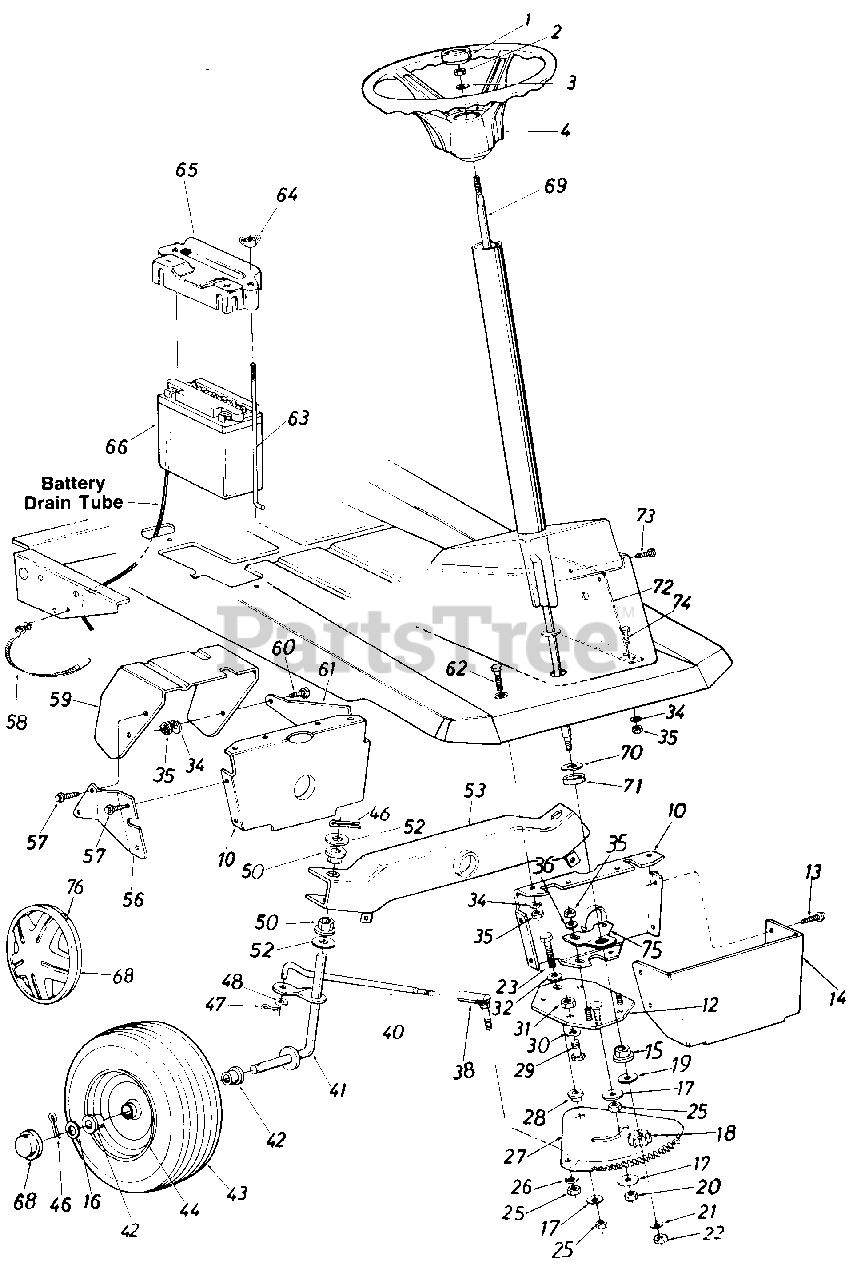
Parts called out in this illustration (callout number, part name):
1	Steering Wheel Cap
2	Hex L-Nut 5/16-24 Thd.
3	Bell-Wash. .345" I.D. x .88" O.D.
4	Steering Wheel Ass'y.
16	Fl-Wash. .64" I.D. x 1.5" O.D.
17	Fl-Wash. 3/8" I.D. x 1.37" O.D.
18	Steering Pinion Gear
19	Fl-Wash. .51" I.D. x 1" O.D.
20	Hex L-Nut 3/8-24
21	Fl-Wash. .34" I.D. x .68" O.D.
22	Hex L-Nut 5/16-24 Thd.
23	Hex Bolt 3/8-24 x 1.5" Lg. (Grade 5)
25	Hex Nut 3/8-24 Thd.
26	L-Wash. 3/8" I.D.
27	Steering Gear Segment
28	Shoulder Spacer .622" Dia. x .21 8
29	Hex Bolt (Nylon) 1/2-13 x .75"
30	Fl-Wash. .530" I.D. x .930"
31	Hex Nut 1/2-13 Thd.
32	Bell-Wash. .385" I.D. x .88"
34	L-Wash. 5/16" I.D.
35	Hex Nut 5/16-18 Thd.
36	Spr. Wash. .32" I.D. x .62" O.D.
38	Ball Joint Ass'y. 3/8-24 Thd.
40	Steering Tie Rod
41	Front Axle Ass'y.-R.H.
42	Flange Bearing .632" I.D.
43	Front Wheel Ass'y. Comp.
44	Front Wheel Rim Only
46	Cotter Pin 1/8" Dia. x 1.25"*
47	Cotter Pin 118" Dia. x 1.00"
48	Fl-Wash. .385" I.D. x .87"
50	Hex Flange Bearing
52	Fl-Wash. .635" I.D. x 1.12"
53	Pivot Bar Ass'y.
58	Cable Tie
59	Clutch-Brake Pedal Ass'y.
60	Hex Bolt 5/16-18 x .75" Lg.
63	Battery Hold Down Rod
64	Wing Nut Solid 1/4-20 Thd.
65	Battery Hold Down Cover
66	12V Battery
69	Steering Shaft Ass'y.
70	Fl-Wash. .62" I.D. x 1.25" O.D.
71	Spacer (Plastic)
74	Hex Bolt 5/16-18 x 2.00" Lg.
75	Steering Gear Adjuster Ass'y.
76	Spring Clip
